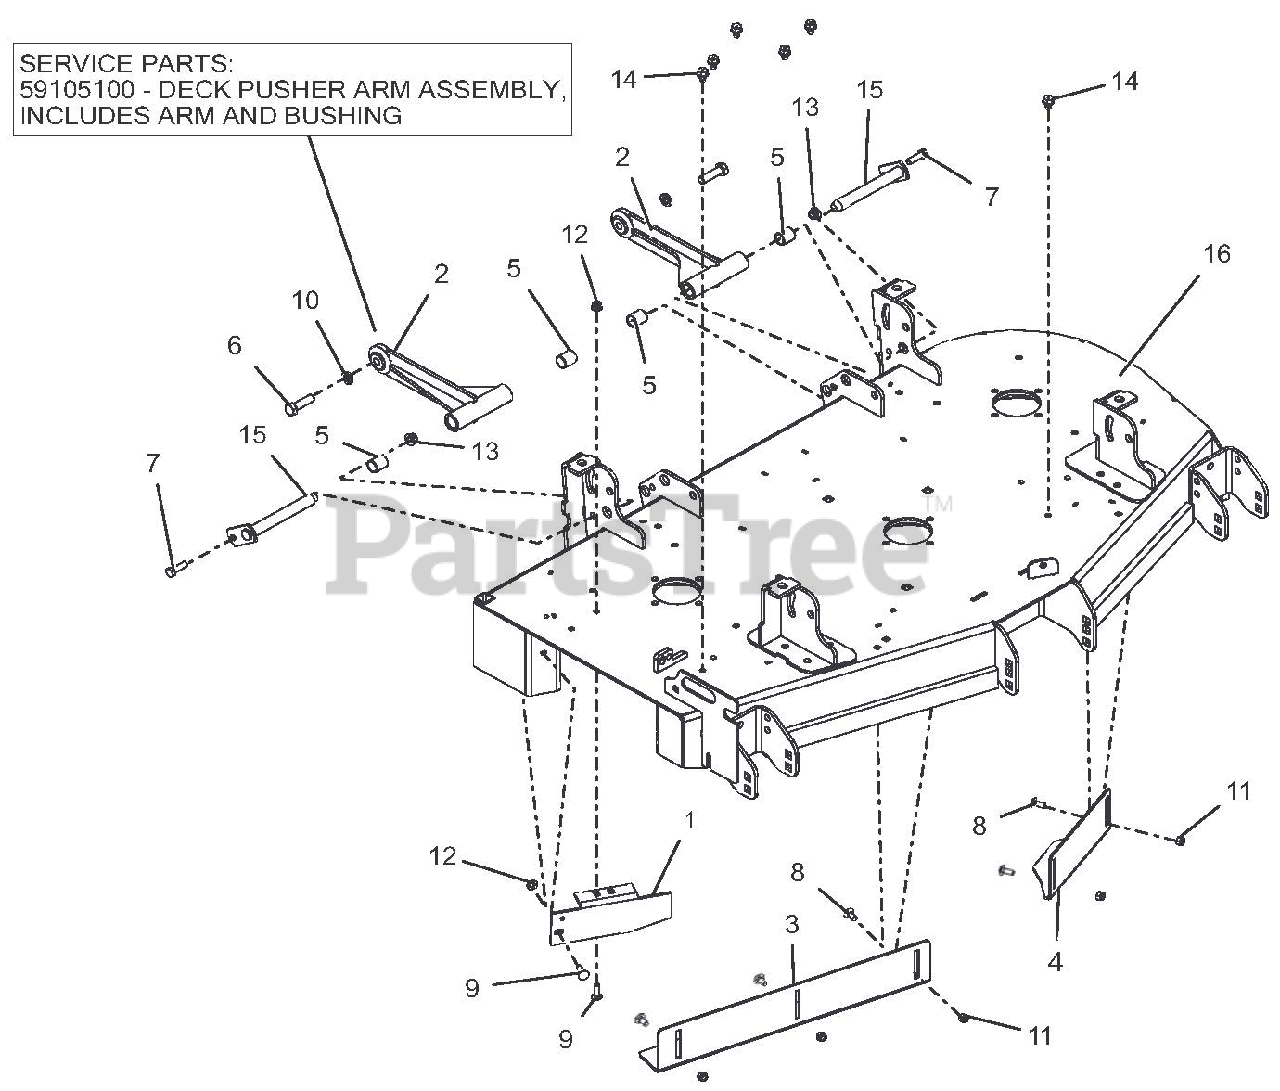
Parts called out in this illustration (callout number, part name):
1	BAFFLE, 44-48" SIDE DISCHARGE
2	WLDMT, DECK PUSHER ARM
2	DECK PUSHER ARM ASSEMBLY
3	BAFFLE, 48" RH VACUUM
4	BAFFLE, 44/48" LH VACUUM
5	BRG, .750 X .875 X 1.000
6	BLT-HEX .50-13X1.75 GR5 YWZC EP80
7	BLT-HEX .38-16X1.25 GR5 YWZC
8	BLT-RDHDSQNK .31-18X.75 G5 YWZC
9	BLT-RDHDSQSHNK .31-18X1.00 G5 Y
10	WSHR-LK .50X.125 REG YWZC
11	NUT-LK-NYL .312-18 YWZC
12	NUT-LK-NYL-FLG .31-18 YWZC
13	NUT-LK-NYL-FLG .38-16 YWZC
14	SCR-TAP .38-16X.50 HWH TR YWZ
15	WLDMT, MOWER MTG. PIN
16	KIT, PT148 MOWER DECK W/SAFETY DECALS-RED
